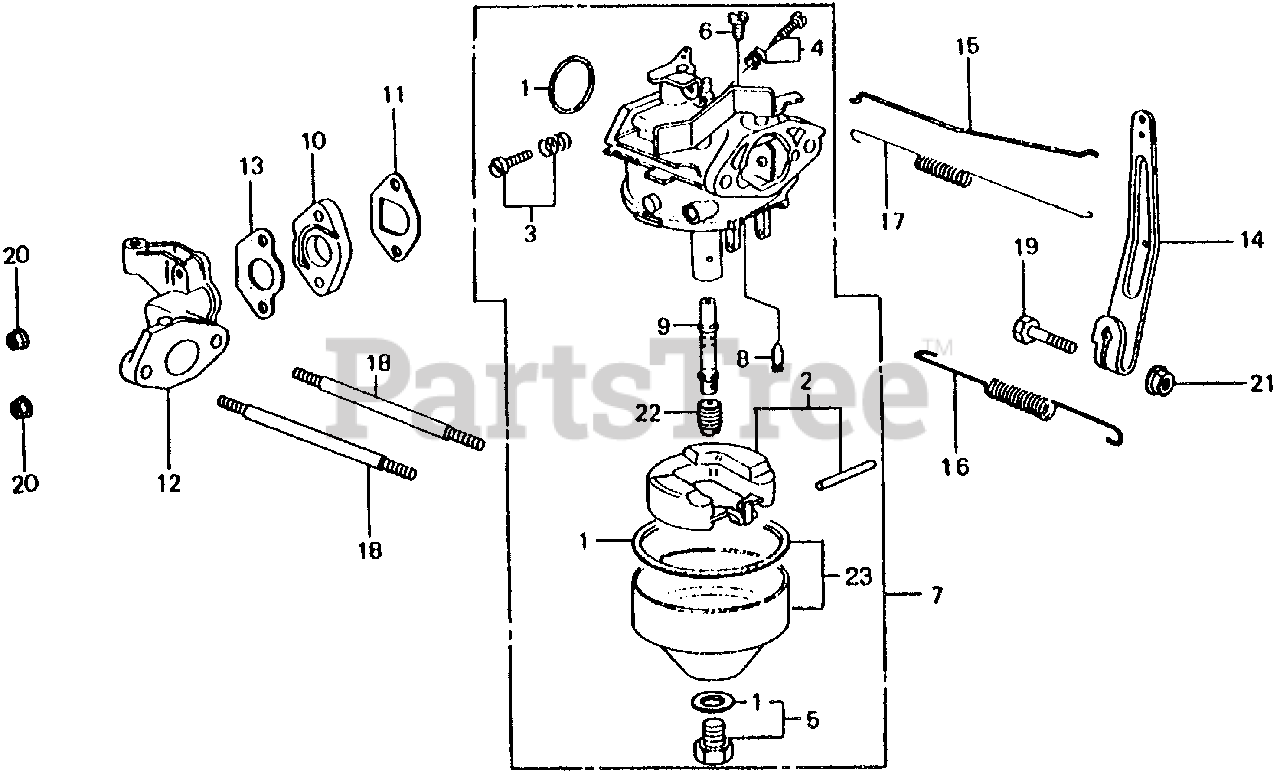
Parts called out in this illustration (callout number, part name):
1	GASKET SET
3	SCREW SET A
4	SCREW SET A
5	SCREW SET B
6	SCREW, PLUG
7	CARBURETOR ASSY.
8	VALVE, FLOAT
9	NOZZLE, MAIN (NOT AVAILABLE)
10	INSULATOR, CARBURETOR
11	GASKET, INSULATOR
12	MANIFOLD, IN. (NOT AVAILABLE)
13	GASKET, IN. MANIFOLD (NOT AVAILABLE)
14	ARM, GOVERNOR
15	ROD, GOVERNOR (NOT AVAILABLE)
16	SPRING, GOVERNOR (NOT AVAILABLE)
17	SPRING, THROTTLE RETURN
18	BOLT, STUD (5X91)
19	BOLT, HEX. (6X20)
20	NUT, FLANGE (5MM)
21	NUT, FLANGE (6MM)
22	JET, MAIN (#45)
22	JET, MAIN (#48)
22	JET, MAIN (#50)
22	JET, MAIN (#52)
22	JET, MAIN (#55)
23	CHAMBER SET, FLOAT
